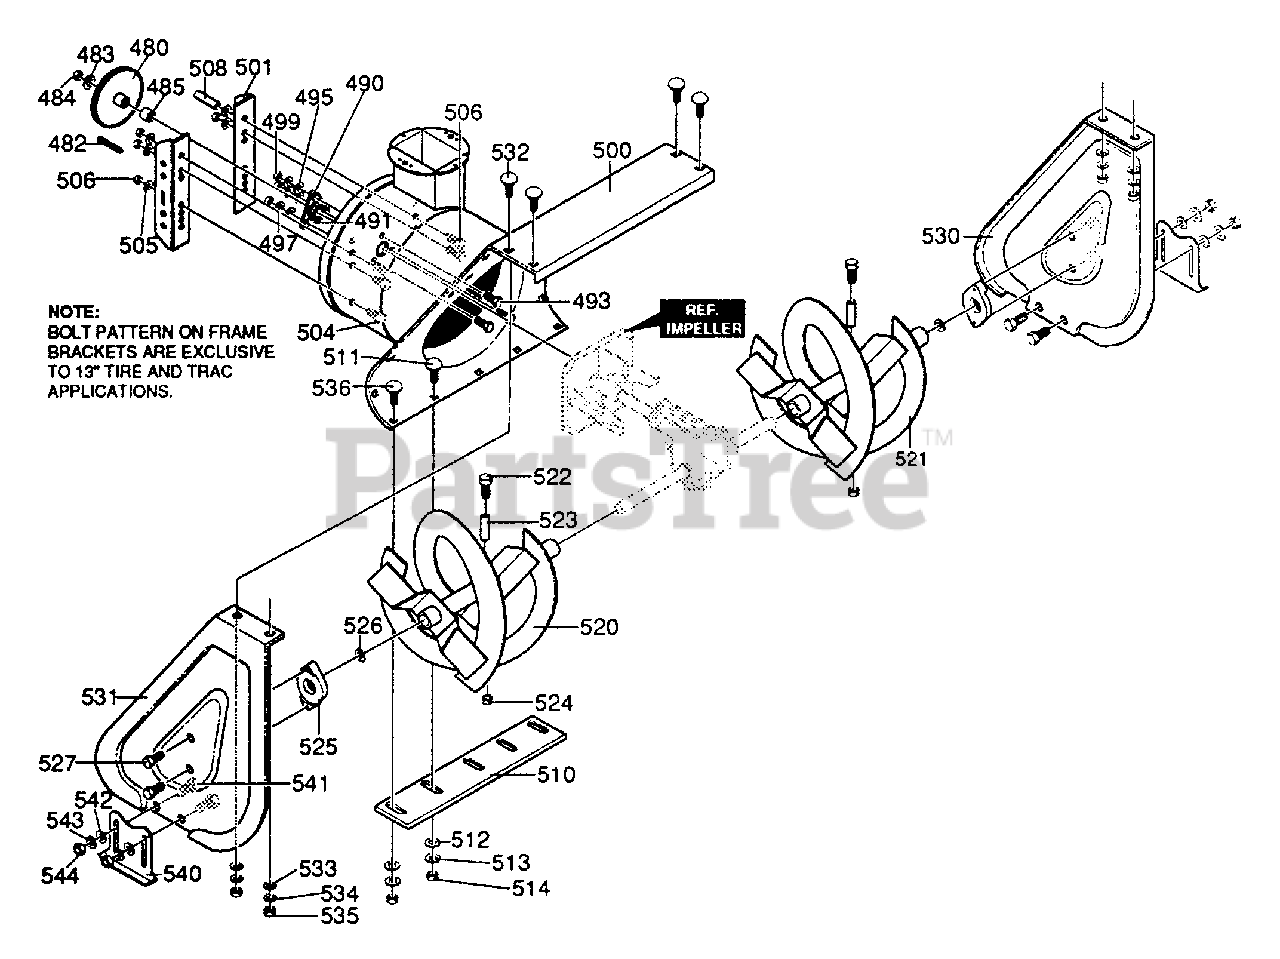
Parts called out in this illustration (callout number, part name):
480	PULLEY, V41- 6.50 OD
482	KEY, SQUARE .18 SQ x .88 LG
483	FLATWASHER, .53 x 1.00 x .063
484	NUT, 1/2-20 REGHXCTRLK
485	SPACER, SLEV .676 x 1.00 x .751
490	RETAINER, BALL BRNG
491	BRNG, BALL 6203-2AA(SEALS)-C3
493	SCREW, 5/16-18x.88 HHC
495	FLATWASHER, .344 x .69 x .065
497	WASHER, HVSPTLK .328 x .60 x .09
499	NUT, 5/16-18 REGHEX
500	HOUSING, ASSY
501	BRACKET & NUTS ASSY
504	SCREW 3/8-16 x .75
505	WASHER .393 x .68 x .10
506	NUT, 3/8-16 REGHEXCTRLK
508	HUB, BRAKE ARM
510	BLADE, SCRAPER, MF 24"
511	BOLT, 5/16-18 x .75 CARRLN
512	FLATWASHER, .344 x .69 x .065
513	WASHER, HVSPTLK .328 x .60 x .09
514	NUT, 5/16-18 REGHEX
520	AUGER, ASSY MF LH 22"
521	AUGER, ASSY MF RH 22"
522	SCREW, 1/4-20 x 1.75 HHCFT
523	SPACER, SLEV .250 x .47 x .20
524	NUT, 1/4-20 REGHEXCTRLK
525	AUGER SHAFT BEARING
526	FLATWASHER, 1.005 x 1.31 x .035
527	SCREW, 5/16-18 x .75 WAHHTAP
530	PLATE, AUGER HSNG END, LH
531	PLATE, AUGER HSNG END, RH
532	BOLT, 5/16-18 x .75 CARRLN
533	FLATWASHER, .344 x .69 x .065
534	WASHER, HVSPTLK .328 x .60 x .09
535	NUT, 5/16-18 REGHEX
536	BOLT, 5/16-18 x 1.00 CARRLN
540	SKID, HEIGHT ADJUST
541	BOLT, 5/16-18 x .75 CARRLNGR2
542	FLATWASHER, .344 x .69 x .065
543	WASHER, HVSPTLK .328 x .60 x .09
544	NUT, 5/16-18 REGHEX
